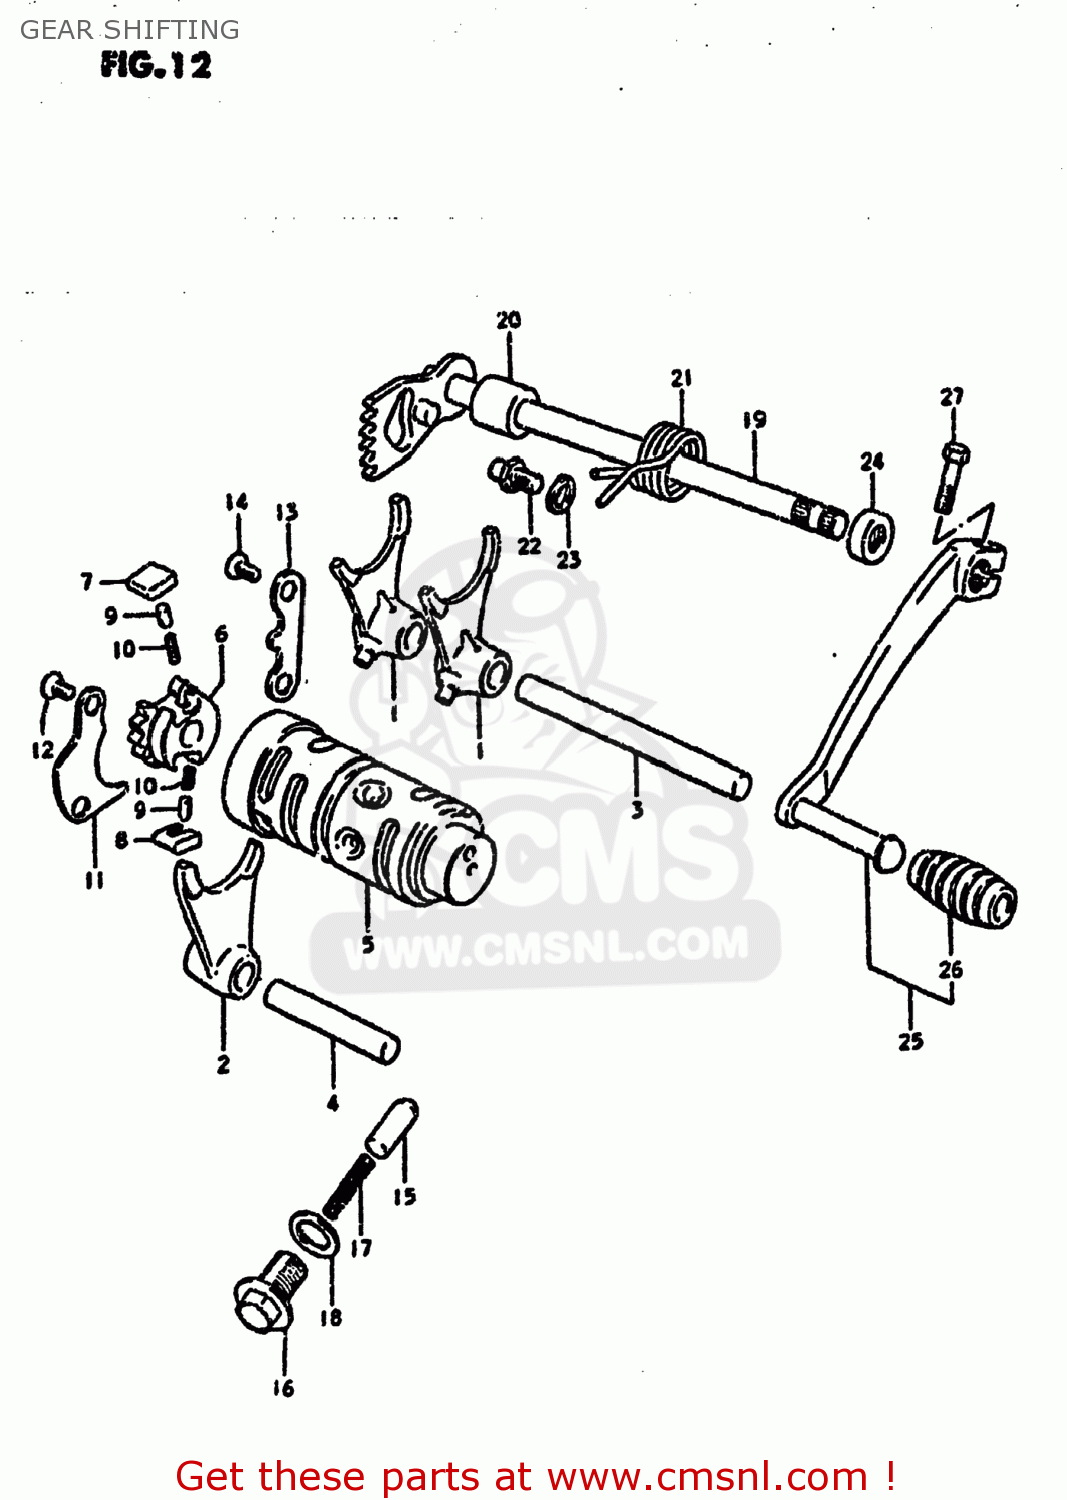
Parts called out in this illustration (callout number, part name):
1	FORK,GEAR SHIFT NO.1
2	FORK,GEAR SHIFT NO.2
3	SHAFT,GEAR SHIFT FORK
4	SHAFT,GEAR SHIFT FORK
5	CAM,GEAR SHIFT
6	RETAINER,GEAR SHIFT CAM
7	PAWL,GEAR SHIFT NO.1
8	PAWL,GEAR SHIFT NO.2
9	PIN(5X8)
10	SPRING
11	LIFTER,GEAR SHIFT PAWL
12	SCREW
13	GUIDE,GEAR SHIFTING CABLE
14	SCREW
15	STOPPER,GEAR SHIFTING
16	BOLT,GEAR SHAFT CAM STOPPER
17	SPRING
18	GASKET(14X19.2X2) (NAS)
19	SHAFT,GEAR SHIFT
20	SPACER(12X20X15.3)
21	SPRING
22	STOPPER,GEAR SHIFT CAM
23	WASHER
24	OIL SEAL
25	LEVER ASSY,GEAR SHIFT
26	RUBBER,GEAR SHIFT PEDAL
27	BOLT
